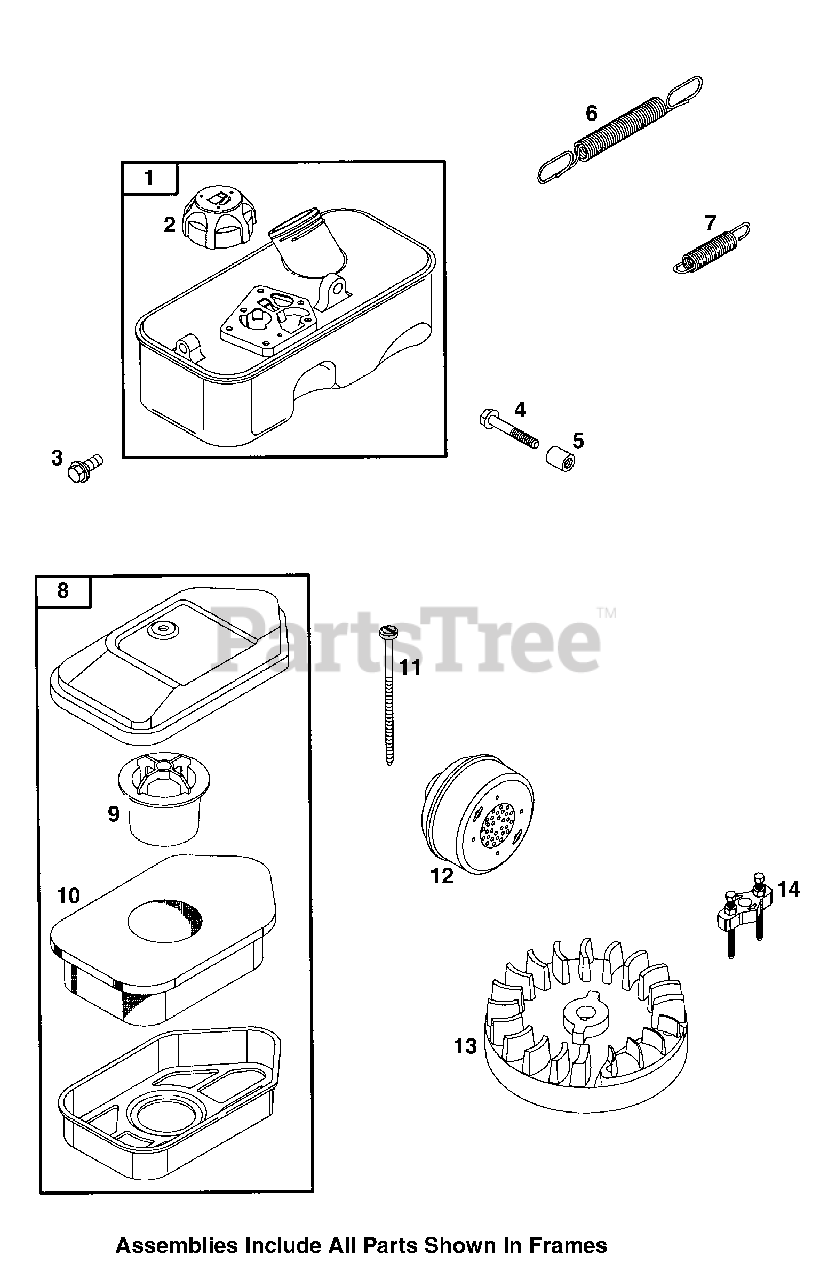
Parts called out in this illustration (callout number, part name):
2	Fuel Tank Cap
3	Hex Screw
4	Hex Screw
5	Fuel Tank Spacer
6	Governor Idler Spring
7	Governor Spring
8	Air Cleaner
9	Air Filter Retainer
10	A/C Foam Filter
11	Slotted Screw
12	Exhaust Muffler
14	Flywheel Puller
